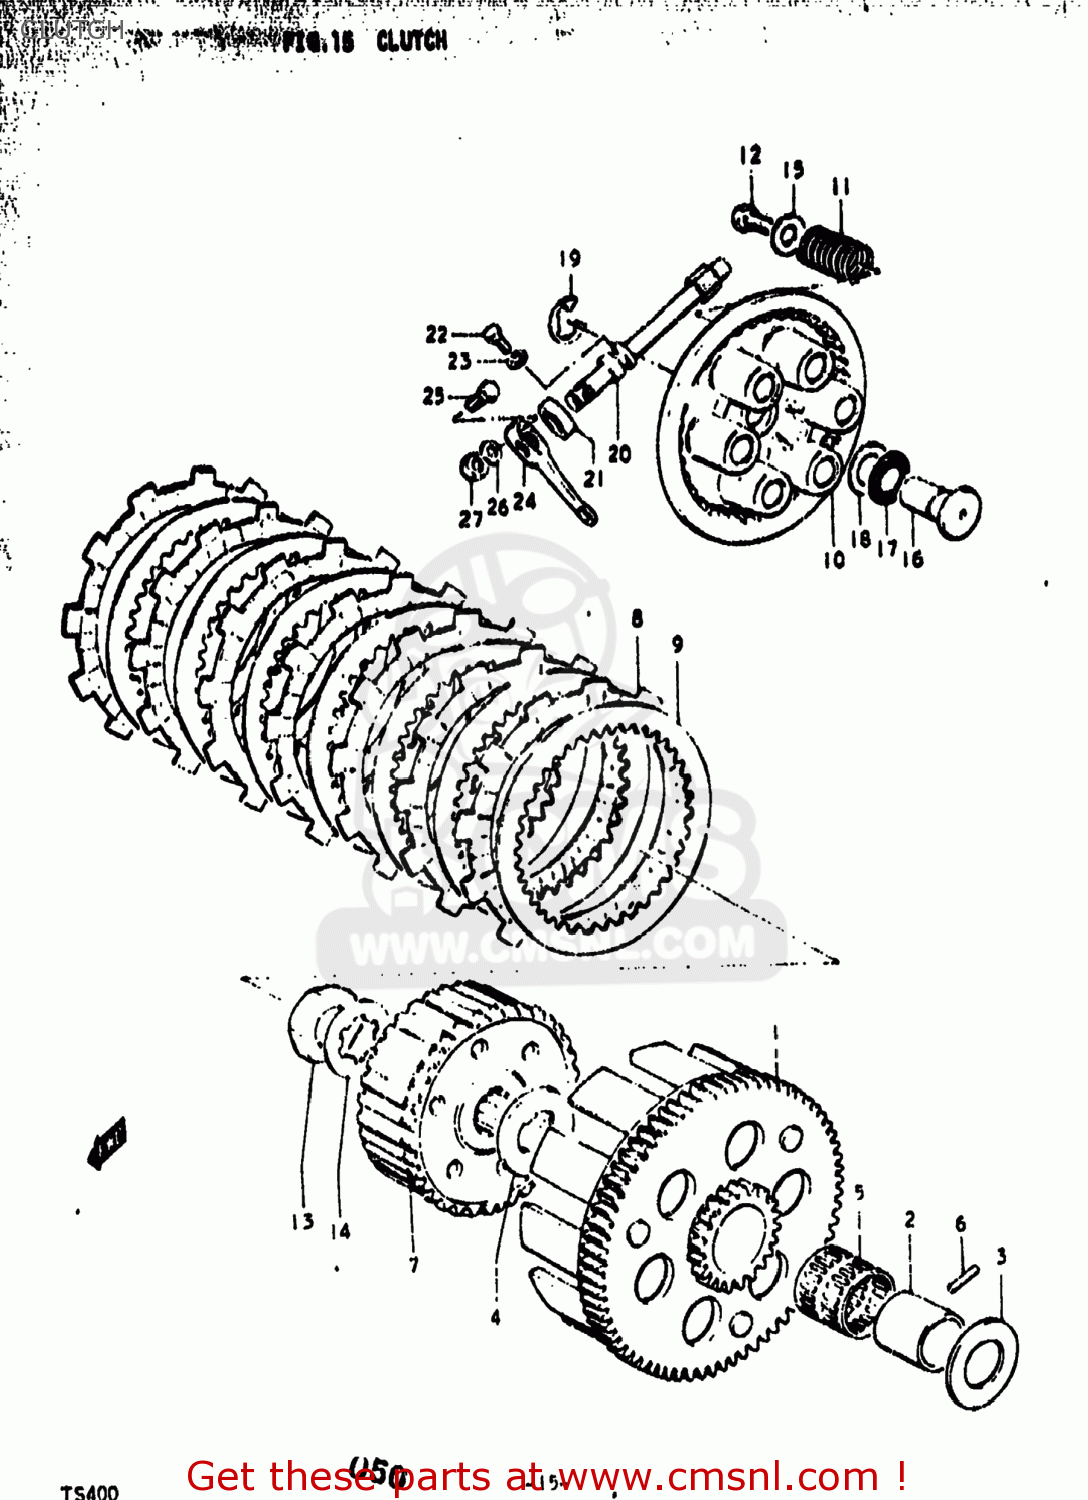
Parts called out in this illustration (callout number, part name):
1	GEAR ASSEMBLY,PRIMARY DRIVE
2	SPACER
3	WASHER
4	WASHER
5	BEARING
6	PIN
7	HUB,CLUTCH SLEEVE
8	PLATE,CLUTCH DRIVE (MCA)
9	PLATE,CLUTCH DRIVEN(T:2.0) (NAS)
10	DISC,CLUTCH PRESSURE
11	SPRING
12	BOLT
13	NUT
14	WASHER,LOCK
15	WASHER
16	RACK,CLUTCH RELEASE
17	BEARING(15X28X2)
18	WASHER
19	E RING 12MM
20	PINION,CLUTCH RELEASE
21	OIL SEAL
22	BOLT(6X12)
23	WASHER
24	ARM,CLUTCH RELEASE
25	BOLT
26	WASHER
27	NUT
